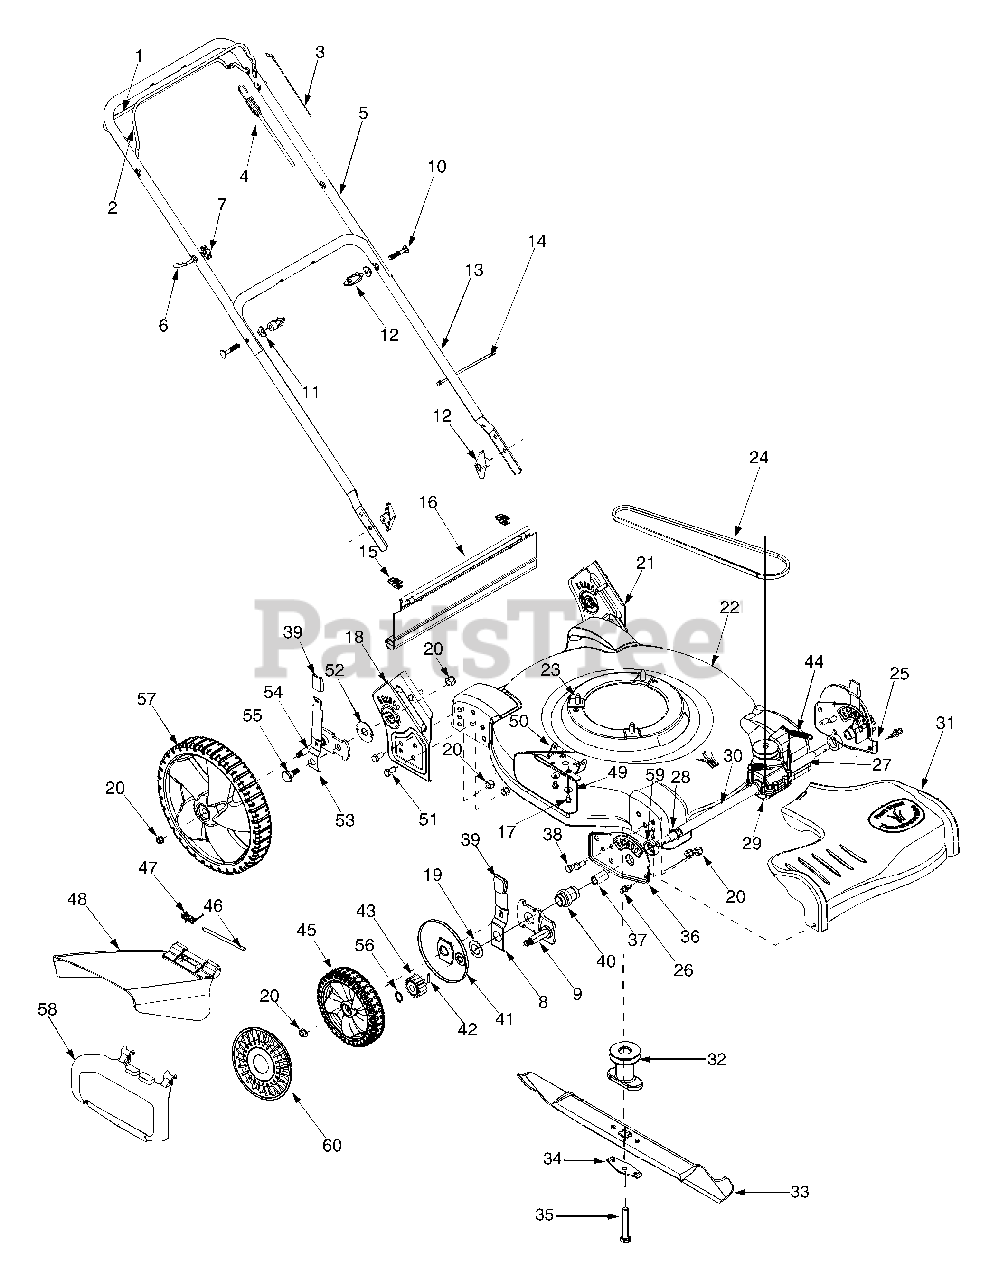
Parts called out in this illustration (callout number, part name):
1	Drive Control Handle
3	Blade Control Cable - 37.75"
4	Drive Control Cable
6	Eye Bolt
7	Wing Nut 1/4-20
8	Spring Lever
9	Pivot Arm Assembly
10	Carriage Bolt 5/16-18 x 2.0
11	Shoulder Washer.320 ID x.93 OD
12	Wing Nut
14	Cable Tie
15	Hinge Clip
16	Trail Shield
17	Hex Screw 1/4-20 x.500
19	Bell Washer,.760 x 1.25 x.041
20	Lock Nut 3/8-16
23	Hex Washer Screw 3/8-16 x 1.0
24	V-Belt, 3L x 33.35
26	Rivet
27	Sleeve Spacer.550 ID x 2.22
28	Retainer Ring
29	Transmission Assembly Complete
30	Sleeve Spacer.550 ID x 7.42
31	Transmission Cover
32	Blade Adapter
33	22" Mulching Blade
34	Bell Blade Support
35	Hex Cap Screw 3/8-24 x 1.5
37	Sleeve Bearing,.502 x.627 x 1.00
38	Hex Cap Screw 3/8-16 x.75
39	Adjustment Knob
40	Bearing Support
41	Wheel Dust Cover
42	Pin
43	Spur Gear 14T - RH
44	Extension Spring.47 OD x 2.50
45	Front Wheel 8 x 1.8
46	Hinge Pin
47	Torsion Spring
48	Side Discharge Assembly
49	Bell Washer.265 ID x.75 OD
50	Deflector Chute Adapter
51	Hex Cap Screw 3/8-16 x.75
52	Thrust Bearing.688 ID x 1.938 OD
53	Spring Lever
54	Rear Pivot Arm Assembly - RH
55	Shoulder Screw 3/8-16
56	Snap Ring.500
57	Rear Wheel 12 x 1.8
58	Mulching Baffle
59	Bearing Support Spacer
60	Hub Cap
